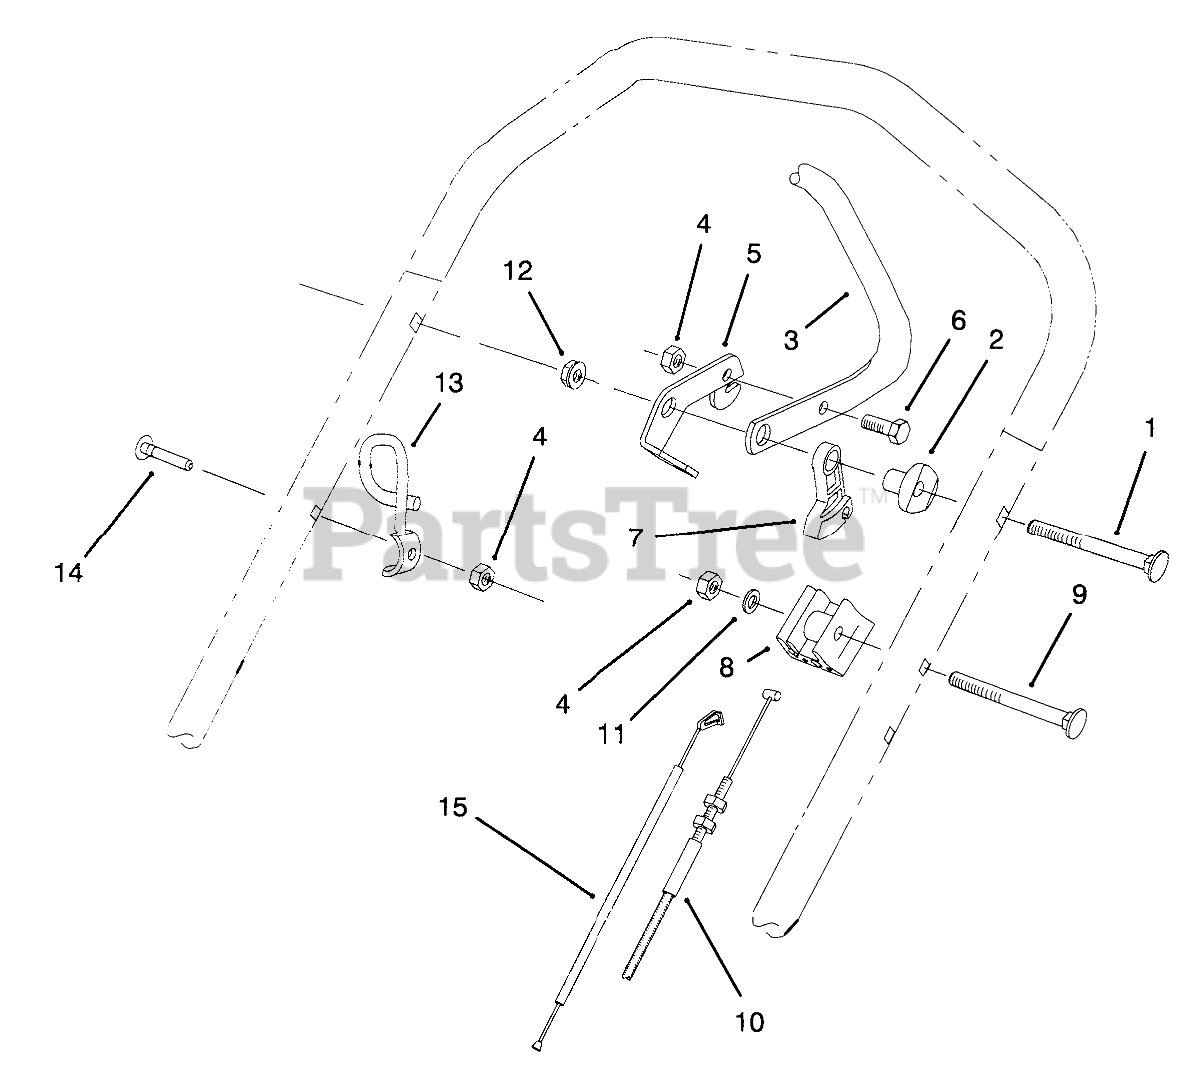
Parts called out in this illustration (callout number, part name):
1	SCREW-HANDLE
2	SPACER-SUPPORT
3	Bar-Control
4	NUT-LOCK, NI
5	LEVER-CONTROL
6	SCREW-HH
7	LEVER-TRACTION
8	SUPPORT-CABLE
9	SCREW-HANDLE
10	TRACTION CABLE
11	WASHER-FLAT
12	NUT-LOCK, NI
13	GUIDE-ROPE
14	Screw-Handle
15	CABLE - BRAKE
